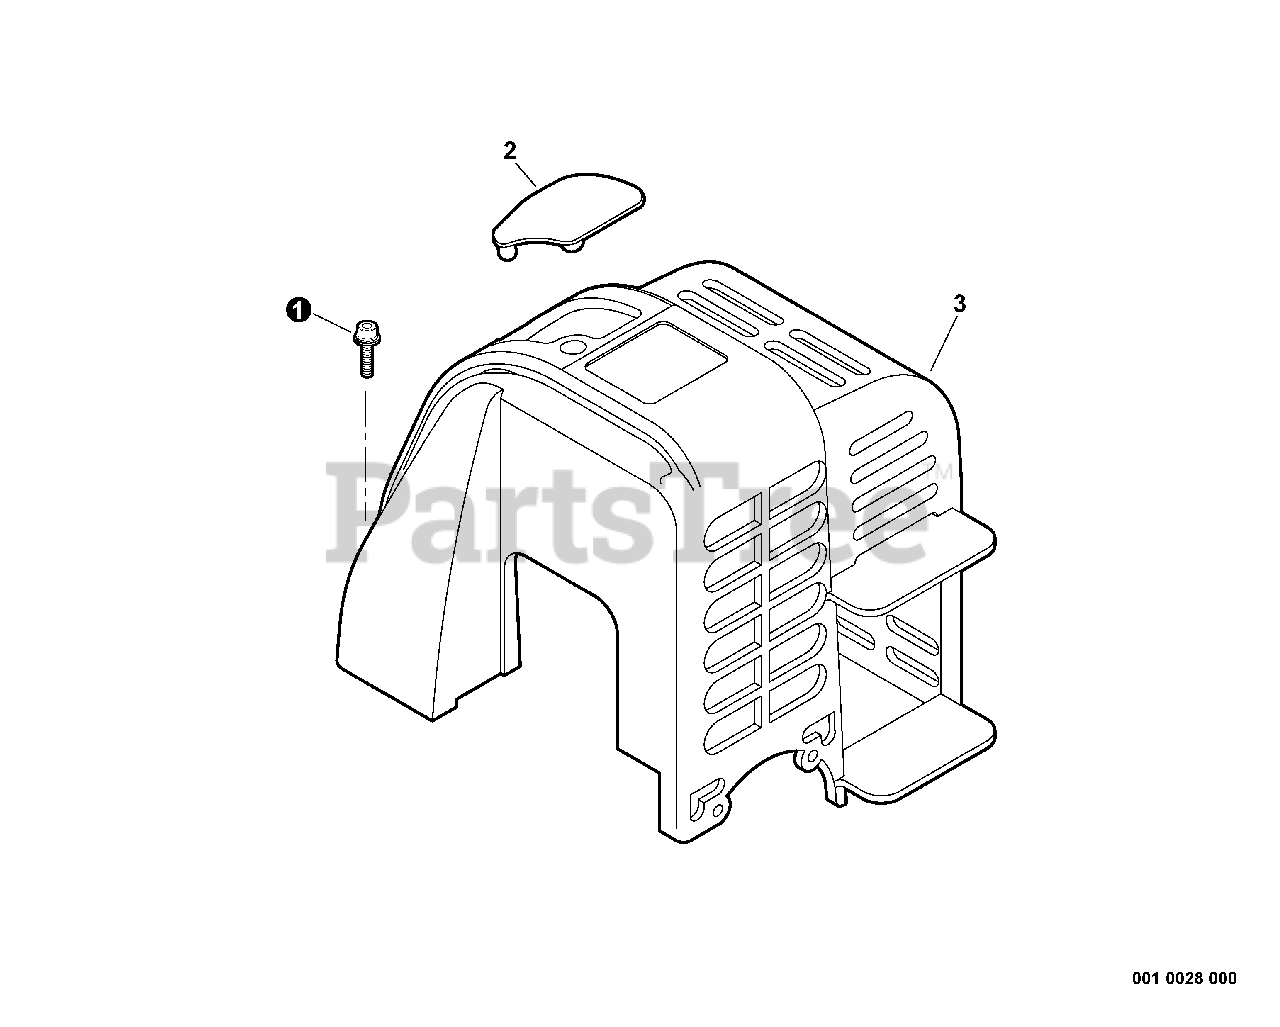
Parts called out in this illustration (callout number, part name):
1	SCREW - 4X16
2	COVER, SPARK PLUG
3	COVER, ENGINE
